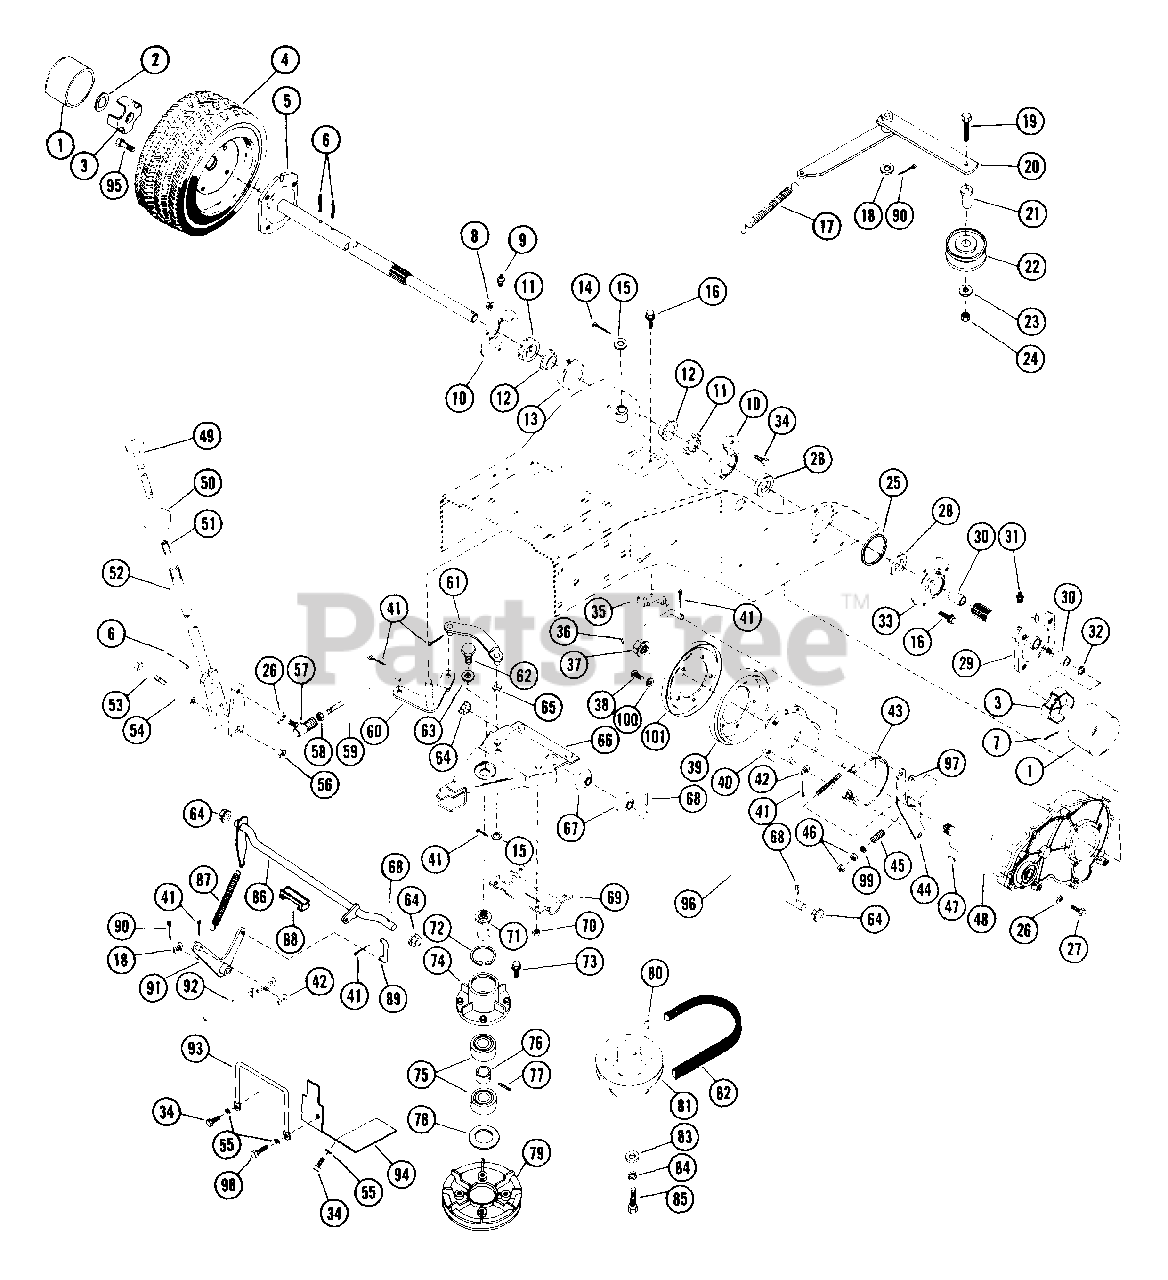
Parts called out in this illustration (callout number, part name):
1	HUB CAP
2	PUSHNUT
3	SPINDLE CUP
4	TERRA TIRE & WHEEL ASSEMBLY
5	R H AXLE SHAFT
6	PIN-ROLL .188X1.50
7	PIN-COTR .12 X 1.25 PL
8	NUT-LK-FLG .250-20 PL
9	ZERK FITTING
10	BEARING FLANGE
11	ADJUSTMENT SPACER
12	BSHG-FLG 1.125X1.31X.50X1.62BR
13	SPHERICAL BUSHING
14	PIN-COTR .12X1.0 PL
15	WSHR-FL-STL .505X.880X.072 PL
16	BLT-SCRHFWH .25-20X.62 PL
17	SG-TENS .091X.73X5.28 WLD 30
18	WSHR-FL-STL .505X1.000X.062
19	BLT-HEX .31-18X1.25 PL GR2
20	IDLER ARM
21	SPCR, BRG .315X.50X.688X.281
22	IDLER
23	WSHR-FL-STL .38X.875X.083 PL
24	NUT-LK .312-18 GR A PL
25	O-RING 2.250X2.234X.139
26	WSHR-LK .312X.097 PL HVY
27	BLT-HEX .31-18X1.50 PL GR2
28	SEAL 1.125X1.624X.250
29	L H AXLE ASSEMBLY
30	BSHG-SLV .750X.814X .750 BRZ
31	HYDRAULIC DRIVE FITTING
32	O-RING .755X.950X.097
33	BEARING FLANGE
34	BLT-HEX .25-20X.50 PL GR2
35	NEUTRAL STOP
36	BRAKE ROD
37	NUT-LK-NYL.625-18 PL
38	BLT-HEX .31-18X.50 PL GR2
39	FRICTION DISC
40	FRICTION DISC HUB
41	PIN-COTR .09X.75 PL
42	WSHR-FL-STL .380X.626X.033
43	BRAKE BAND
44	BRAKE LEVER
45	SG-COMP .092X.375X2.53
46	NUT-HEX .312-18
47	KEY-WDRF .188X.875X.375 SAE11
48	GEAR CASE ASSEMBLY
49	SHIFT CONTROL ROD
50	SHIFT BALL
51	SG-COMP ??X.44X?? WLD 10
52	SHIFT LEVER
53	BLT-HEX .38-16X2.50 PL GR2
54	SHIFT SPACER
55	WSHR-LK .250X.077 HVY PL
56	NUT-LK-CTR .375-16 GR A PL
57	SNAP IN BALL JOINT
58	NUT-HEX .312-24 PL
59	SHIFT ROD
60	SHIFT LEVER
61	SHIFT LINK
62	SPINDLE STUD
63	WSHR-LK-EXT .500X.040 MED
64	FLANGE BUSHING
65	BSHG-FLG .372X.500X.312X.625NY
66	SPINDLE MOUNTING PLATE
67	BEARING
68	PIN-ROLL .188X1.13
69	BEARING RETAINER
70	NUT-LK-CTR .250-20 PL
71	SPINDLE
72	SNAP RING KIT
73	BLT-SERHFWH .25-20X.75 PL
74	SPINDLE HOUSING
75	BRG-BALL .751X1.78X.61
76	SPACER .753X1.000X.457
77	PIN-ROLL .188X1.00
78	WSHR-FL-STL 1.375X2.125X.075
79	DRIVE DISC
80	KEY-WDRF .156X.625X.25 SAE 6
81	ENGINE SHEAVE
82	V-BELT, SAE 380-RAW EDGE
83	WSHR-FL-STL .438X1.125X.19
84	WSHR-LK .375X.115 HVY PL
85	BLT-HEX .38-24X1.25 BLKO GR5
86	CLUTCH SHAFT
87	SG-TENS .062X.68X6.0 WLD 10
89	LINK PIN
90	PIN-COTR .09X1.0 PL
91	CLUTCH LEVER
92	CLUTCH ROD
93	BELT GUIDE
94	SPLASH GUARD
95	BLT-WHL .50-20X.50 GR5 PL
96	HINGE SHAFT
97	WSHR-FL-STL .382X.812X.023 PL
98	BLT-HEX .25-20X.75 PL GR2
99	WSHR-FL-STL .323X.625X.062 PL
100	WSHR-LK-INT .313X.030 PL
